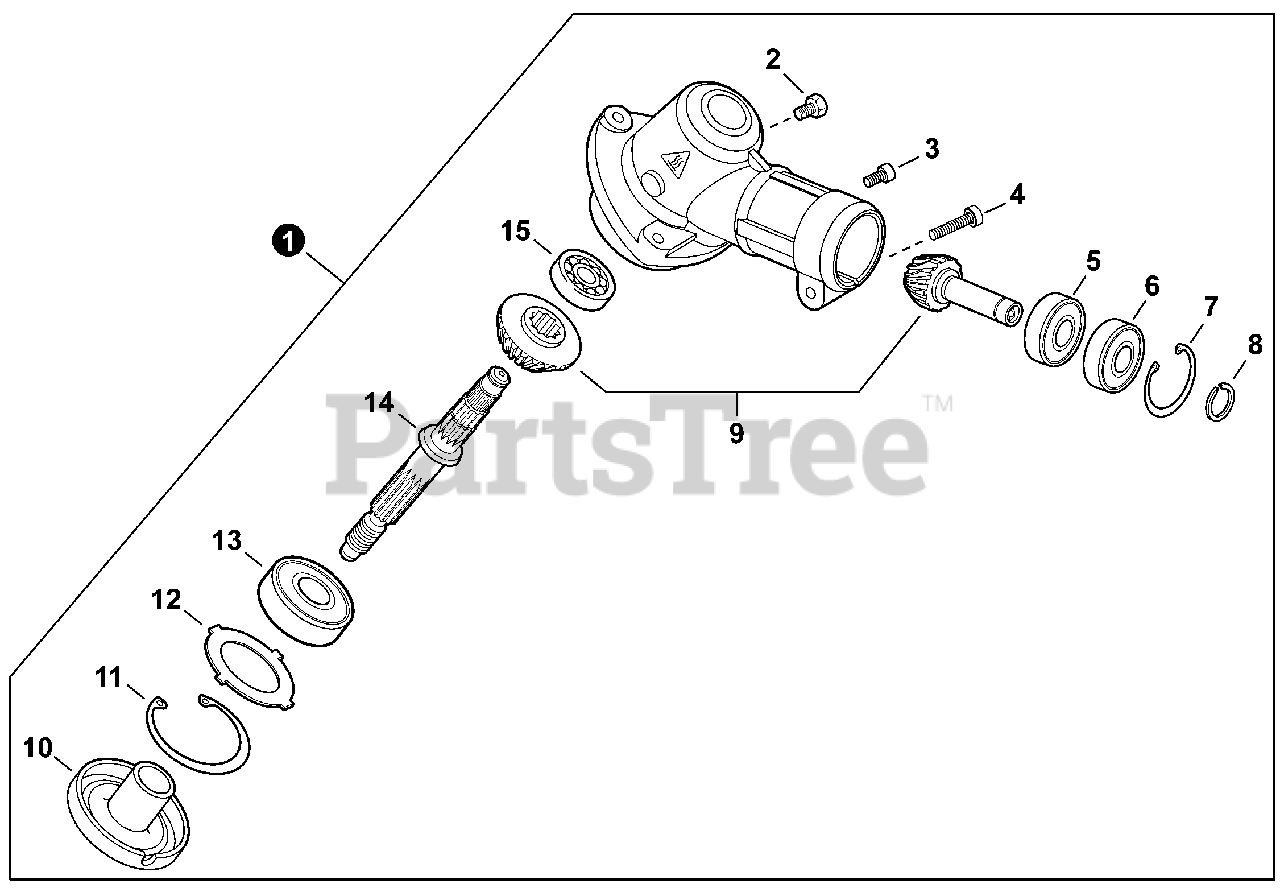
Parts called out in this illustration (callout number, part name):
1	GEAR CASE ASSY
2	BOLT M8×8
3	BOLT, TORX 5×10
4	BOLT, TORX 5×25
5	BEARING, BALL
6	BEARING, BALL
7	RING, SNAP Ø25
8	RING, SNAP Ø9
9	GEAR SET
10	PLATE, ADAPTOR - UPPER
11	RING, SNAP Ø32
13	BEARING, BALL 6201
14	SHAFT, GEAR
15	BEARING, BALL
